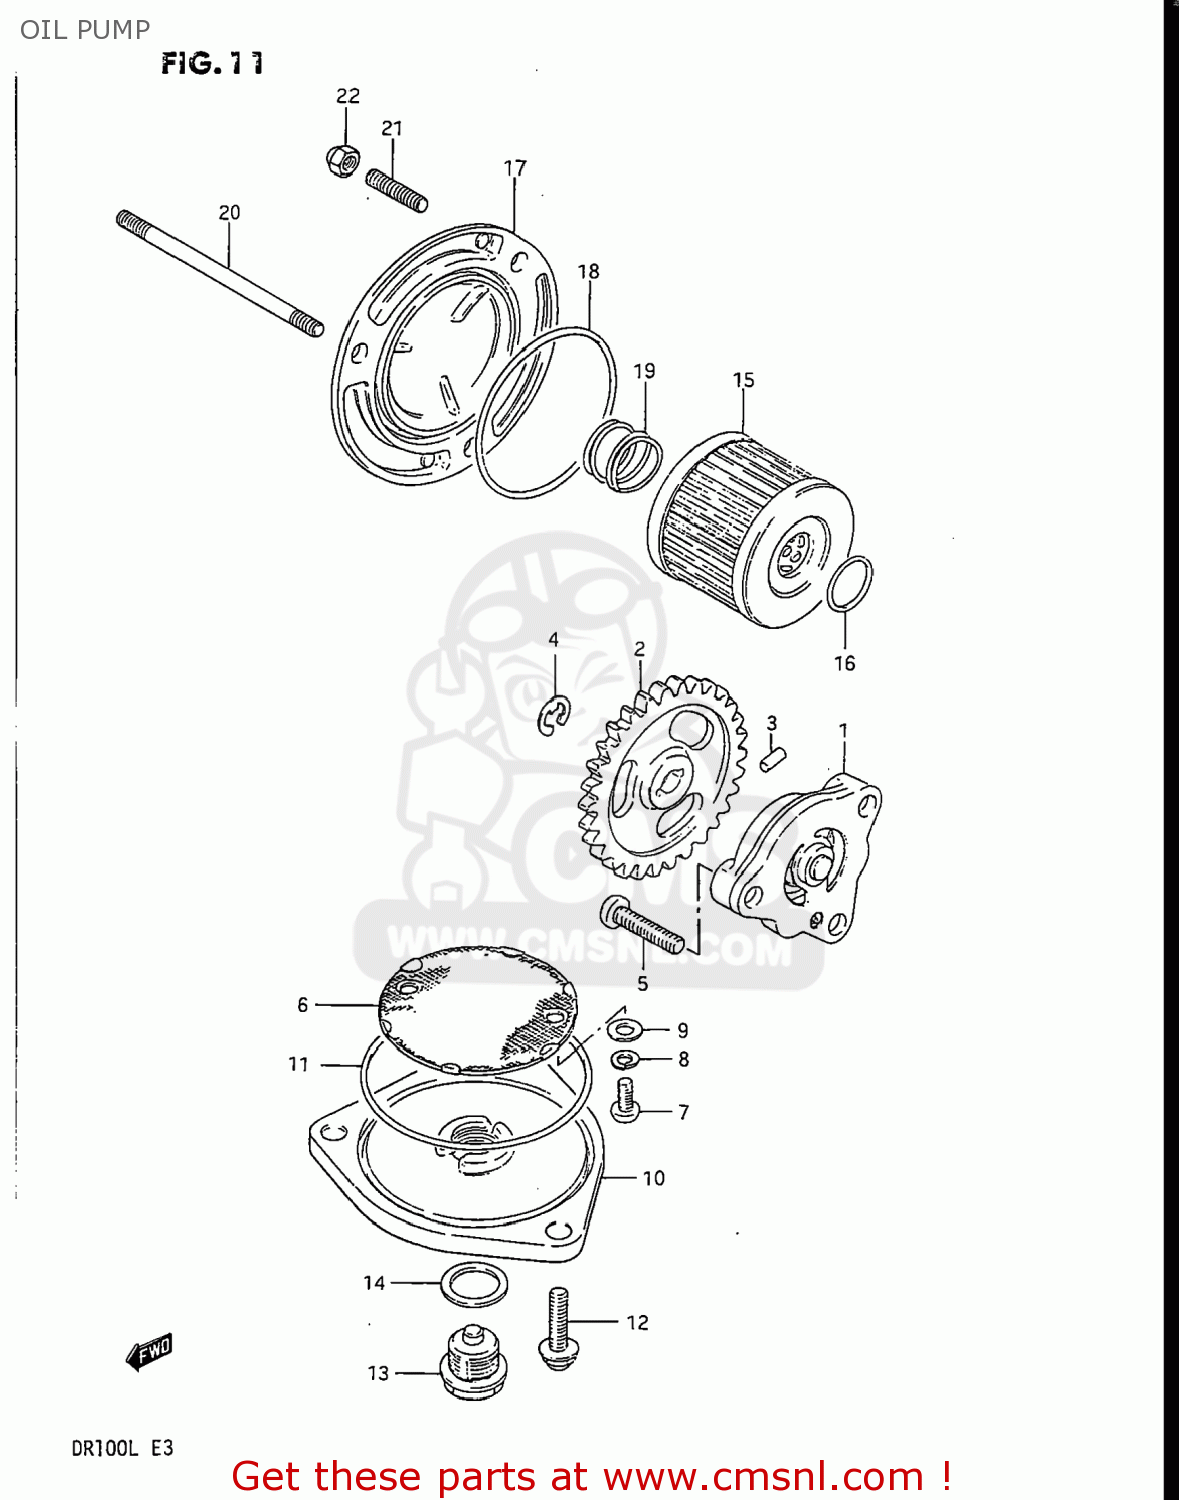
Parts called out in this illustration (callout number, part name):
1	PUMP ASSEMBLY,OIL
2	GEAR,ENG OIL PUMP DRIVEN(NT:30
3	PIN(2.5X11.8)
4	E RING 6MM
5	SCREW
6	STRAINER,ENGINE OIL
7	SCREW 5X12
8	LOCK WASHER
9	WASHER
10	CAP,OIL STRAINER
11	O RING(D:2.4,ID:60.5)
12	BOLT
13	PLUG
14	GASKET(14X19.2X2) (NAS)
15	FILTER ASSY,ENGINE OIL
16	O RING(D:1.9,ID:13)
17	CAP,OIL FILTER
18	O RING(D:2.4,ID:52.6)
19	SPRING
20	STUD BOLT, 6X8
21	STUD 6X12
22	NUT 6MM
